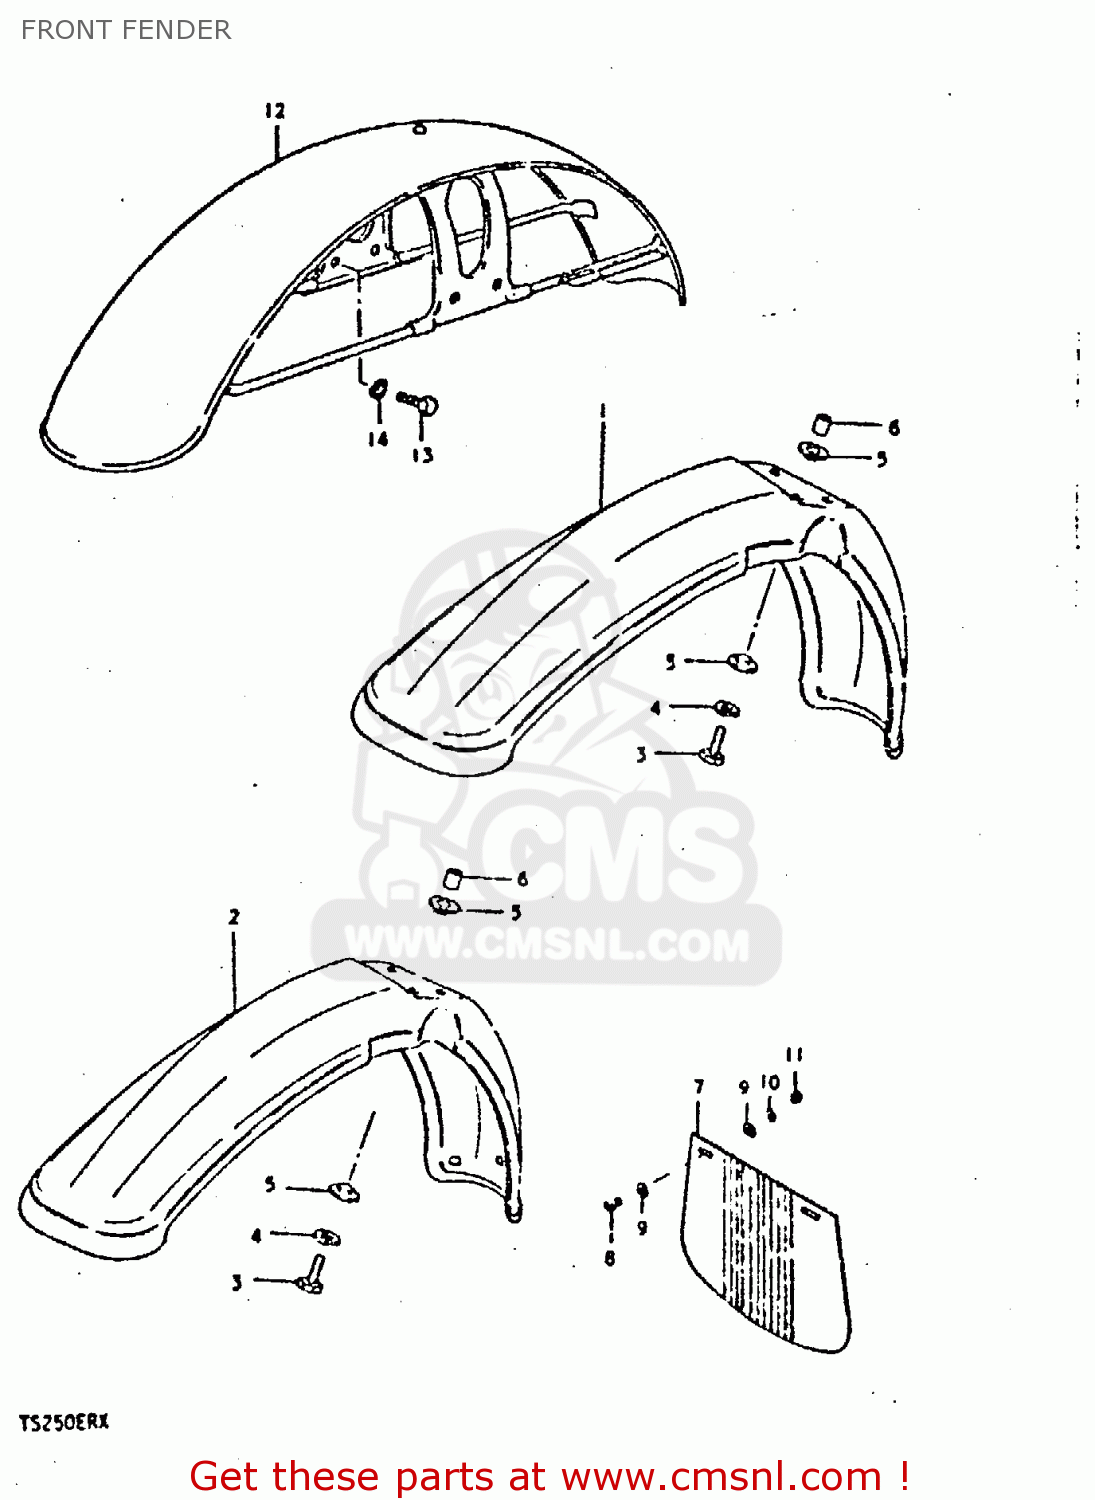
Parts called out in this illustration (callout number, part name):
1	FENDER,FR
3	BOLT
4	LOCK WASHER
5	SPACER
6	SPACER
12	FENDER,FR
13	BOLT
14	LOCK WASHER
